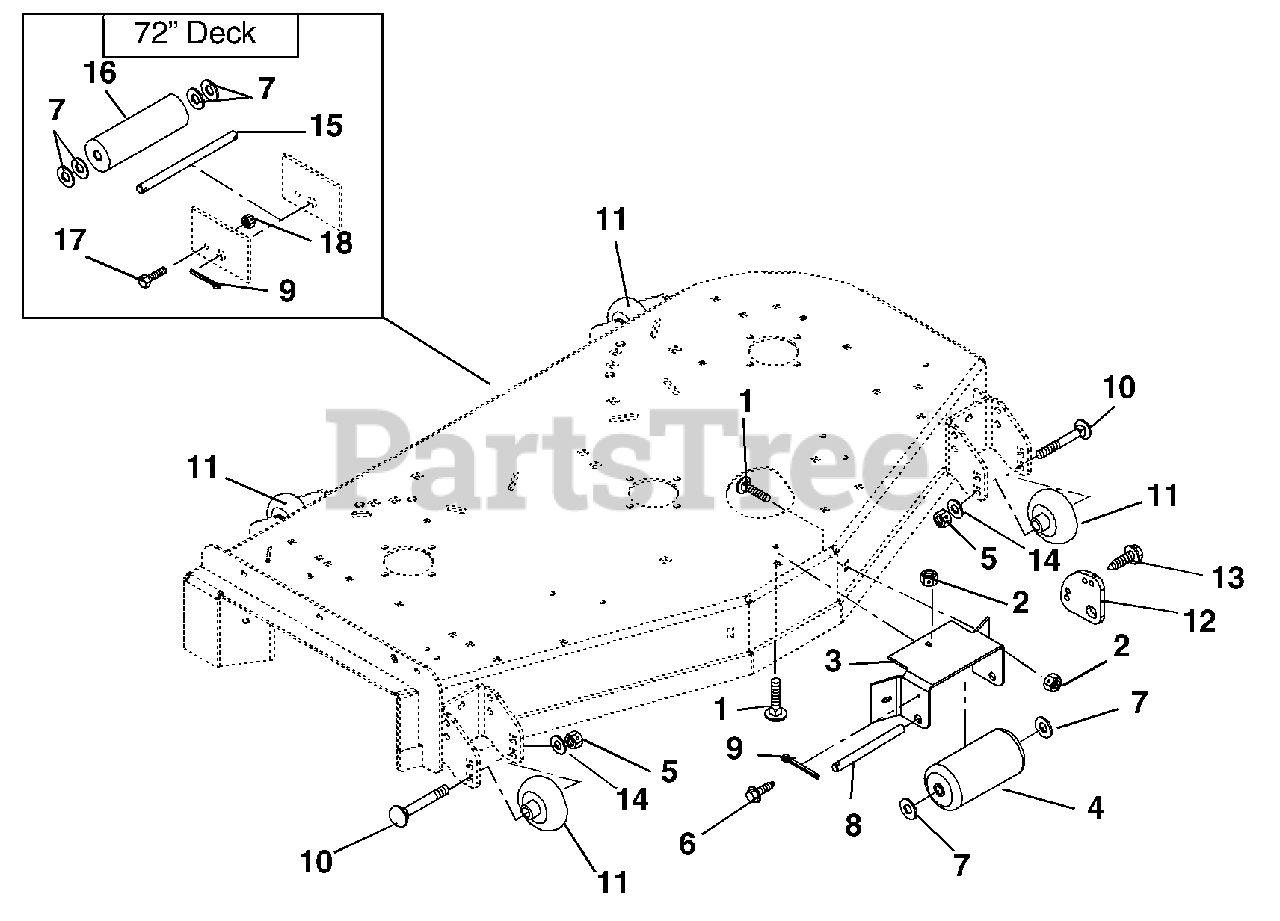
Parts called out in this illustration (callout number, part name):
1	Bolt-Round Head Square Neck .38-16 x 1.00 Grade 5
2	Nut-Locking-Top-Flange .38-16
3	Bracket- Anti-Scalp Roller
5	Nut-Locking-Nylon .50-13
6	Screw-Tapping .25-20 x .75 Hex Washer Head
7	Washer-Flat-Steel .656 x 1.31 x .095 (073, 075, 318, 319)
7	Washer-Flat-Steel .656 x 1.31 x .095 (074, 076)
9	Pin-Cotter .25 x 2.00 (073, 075, 318, 319)
9	Pin-Cotter .25 x 2.00 (074, 076)
10	Bolt-Round Head Square Neck .50-13 x 5.00 Grade 2
11	Wheel, 3 x 5
12	Anti-Scalp Washer
13	Screw-Tapping .25-20 x .62 Hex Washer Head
14	Washer-Flat-Steel .531 x 1.06 x .095
15	Shaft, Center Roller (074, 076)
16	Roller, Gage (074, 076)
17	Bolt-Hex .25-20 x .75 Grade 5 (074, 076)
18	Nut-Locking-Center .25-20 (074, 076)
